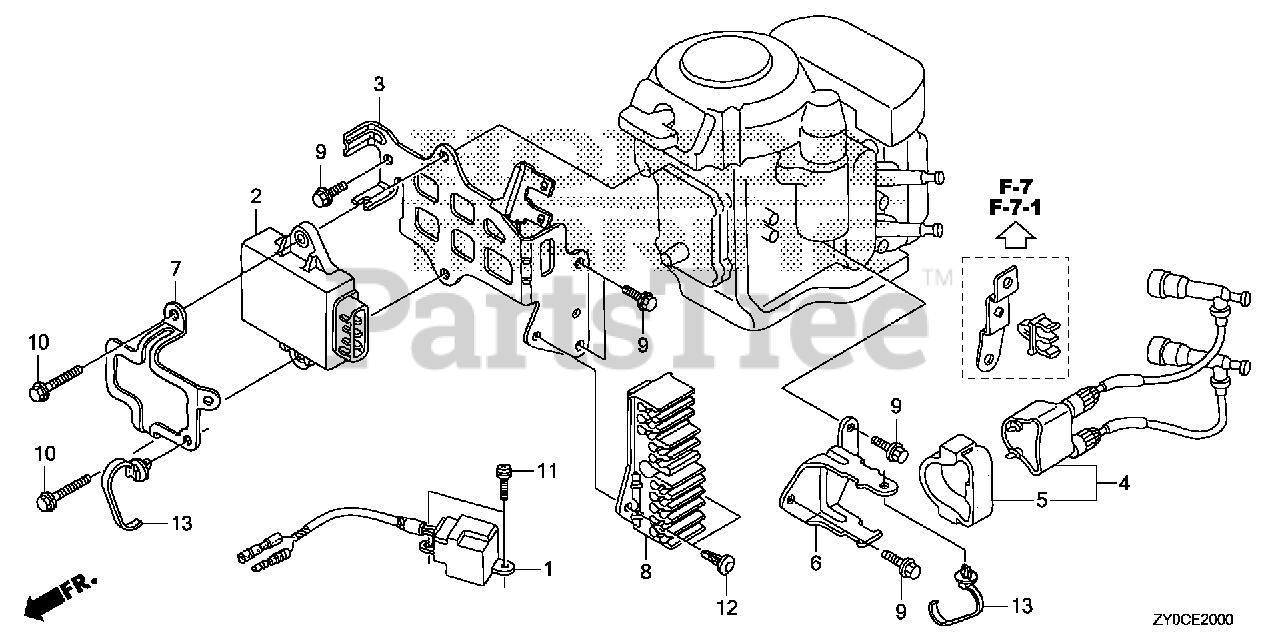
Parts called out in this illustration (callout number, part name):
1	COIL ASSY., PULSER
2	MODULE, IGNITION CONTROL (CDI)
3	PLATE, C.D.I. (REMOTE CONTROL)
4	COIL ASSY., IGNITION
5	SUSPENSION, IGNITION COIL
6	BRACKET, IGNITION COIL
7	BRACKET, C.D.I.
8	BRACKET, CONNECTOR
9	BOLT, FLANGE (6X14) (CT200)
10	BOLT, FLANGE (6X25)
11	SCREW-WASHER (5X16)
12	CLIP, ANCHOR
13	CLIP, HARNESS BAND (151.5MM) (NATURAL)
